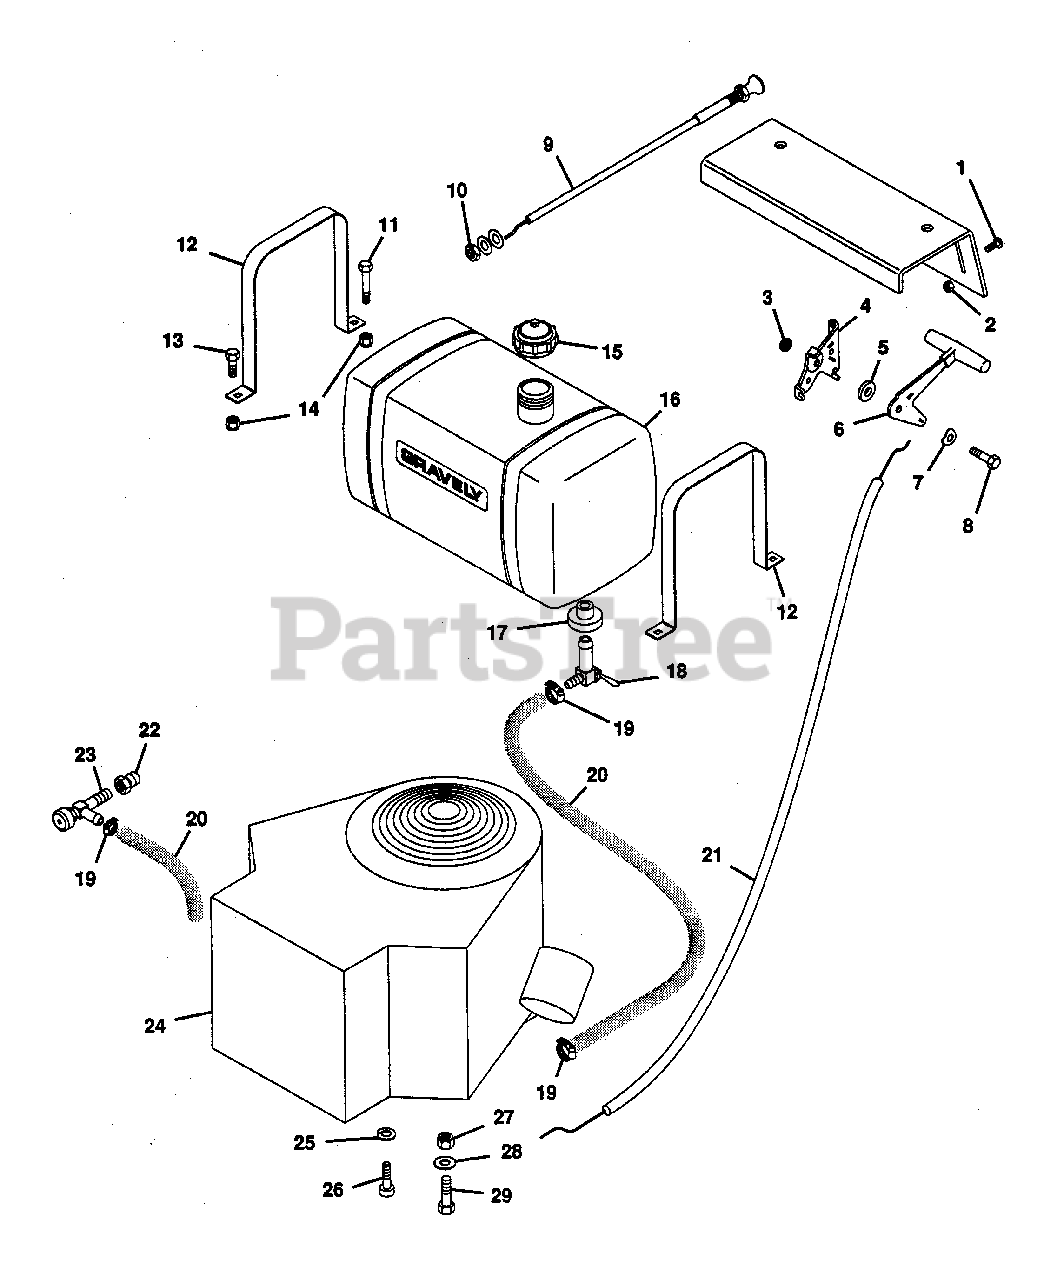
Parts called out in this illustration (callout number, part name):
1	Screw, Mach. 10-32x.50 PHD
2	Nut, Lock 10-32
3	Nut, Lock 1/4-28
4	Bracket, Mounting L.H.
5	Washer, Friction
6	Assembly, Knob and Lever
7	Washer, Spring
8	Bolt, Hex 1/4-28x.75
9	Control, Choke
10	Nut, Jam 3/8-24 Hex
11	Bolt, Hex 1/4-20x1.75
12	Strap, Fuel Tank
13	Bolt, Hex 1/4-20x.625
14	Nut, Lock 114-20
15	Cap, Fuel Tank
16	Tank, Fuel
17	Bush., Flg..375x1.06x.625 Rb.
18	Valve, Ball Shut-off
19	Clamp, Hose
20	ft. Line, Fuel
21	Assembly, Throttle Conduit
22	Adaptor, Oil Drain
23	Cock, Oil Drain
24	Engine, 16 HP B&S
24	Muffler Kit
25	Washer, Lock 5/16 Reg.
26	Screw, M8x1.25x20mm SHD
27	Nut, Lock 5/16-18
28	Washer, Flat .344x.688x.065
29	Bolt, Hex 5/16-18x1.50
